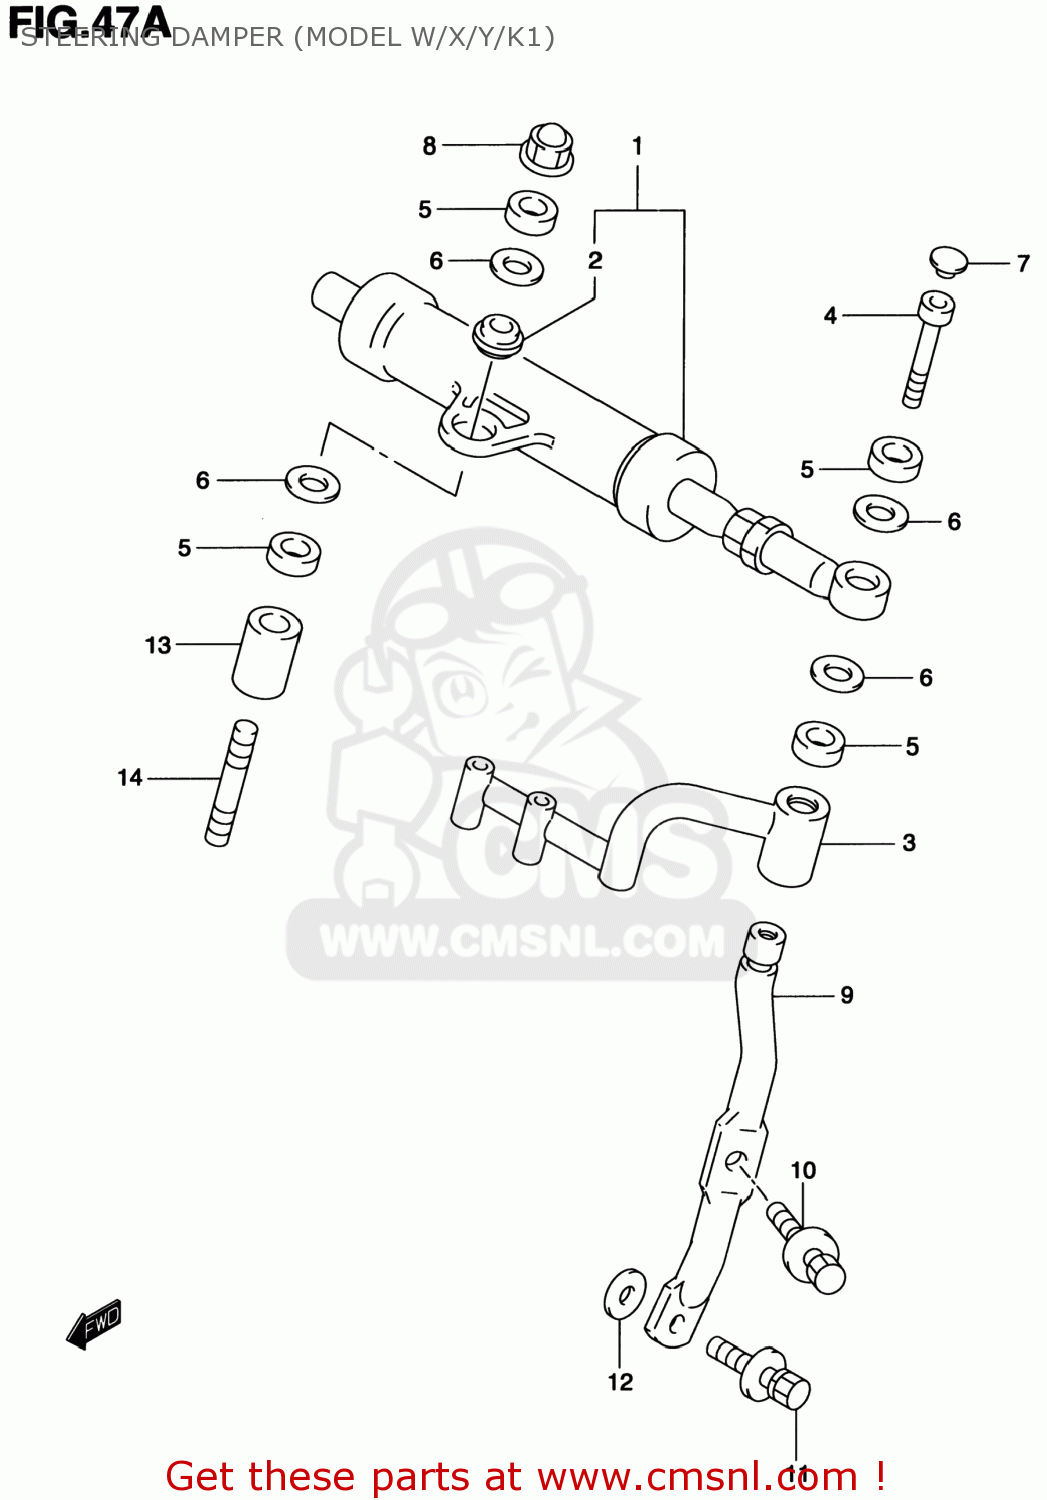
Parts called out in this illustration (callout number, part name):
1	DAMPER ASSY,STEERING
2	BEARING(8X17.5X11)
3	STAY,STEERING DAMPER
4	BOLT
5	6
6	SHIM(8X12X0.8)
7	CAP(OD:11)
8	NUT
9	ROD,STEERING DAMPER
10	BOLT(6X30)
11	BOLT,STAY,LOWER 6X35
12	WASHER(6.5X20X1.6)
13	SPACER,STEERING DAMPER
14	BOLT,STUD(8X50)
